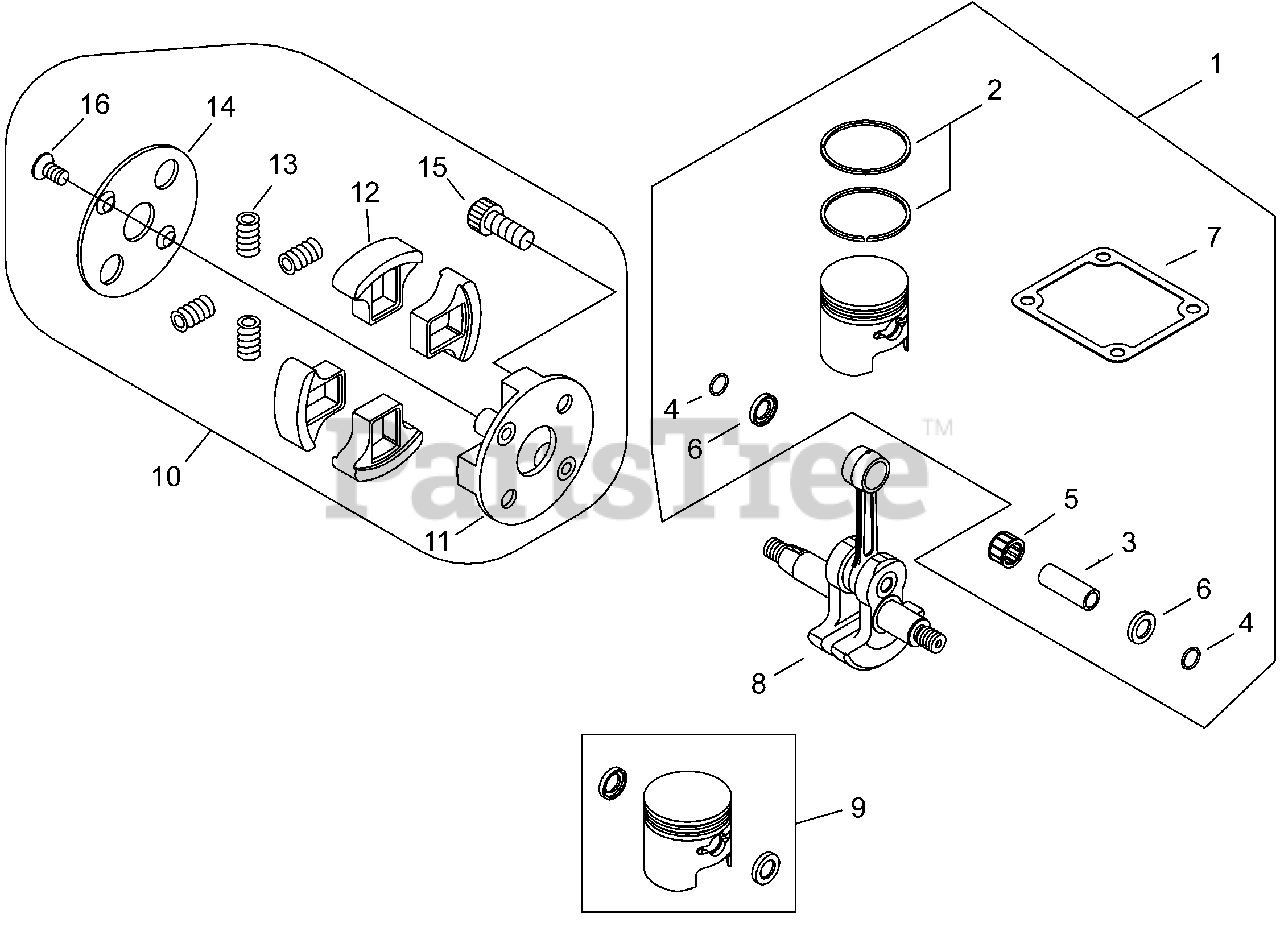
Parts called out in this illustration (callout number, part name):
1	PISTON KIT
2	RING, PISTON
3	PIN, PISTON 10
4	RING, SNAP
5	BEARING, NEEDLE 10
6	WASHER, THRUST
7	GASKET, CYLINDER
8	CRANKSHAFT ASSY
9	PISTON SET
10	CLUTCH ASSY
11	BOSS, CLUTCH
12	SHOE, CLUTCH
13	SPRING, CLUTCH
14	PLATE, CLUTCH
15	BOLT, CLUTCH
16	BOLT 5
